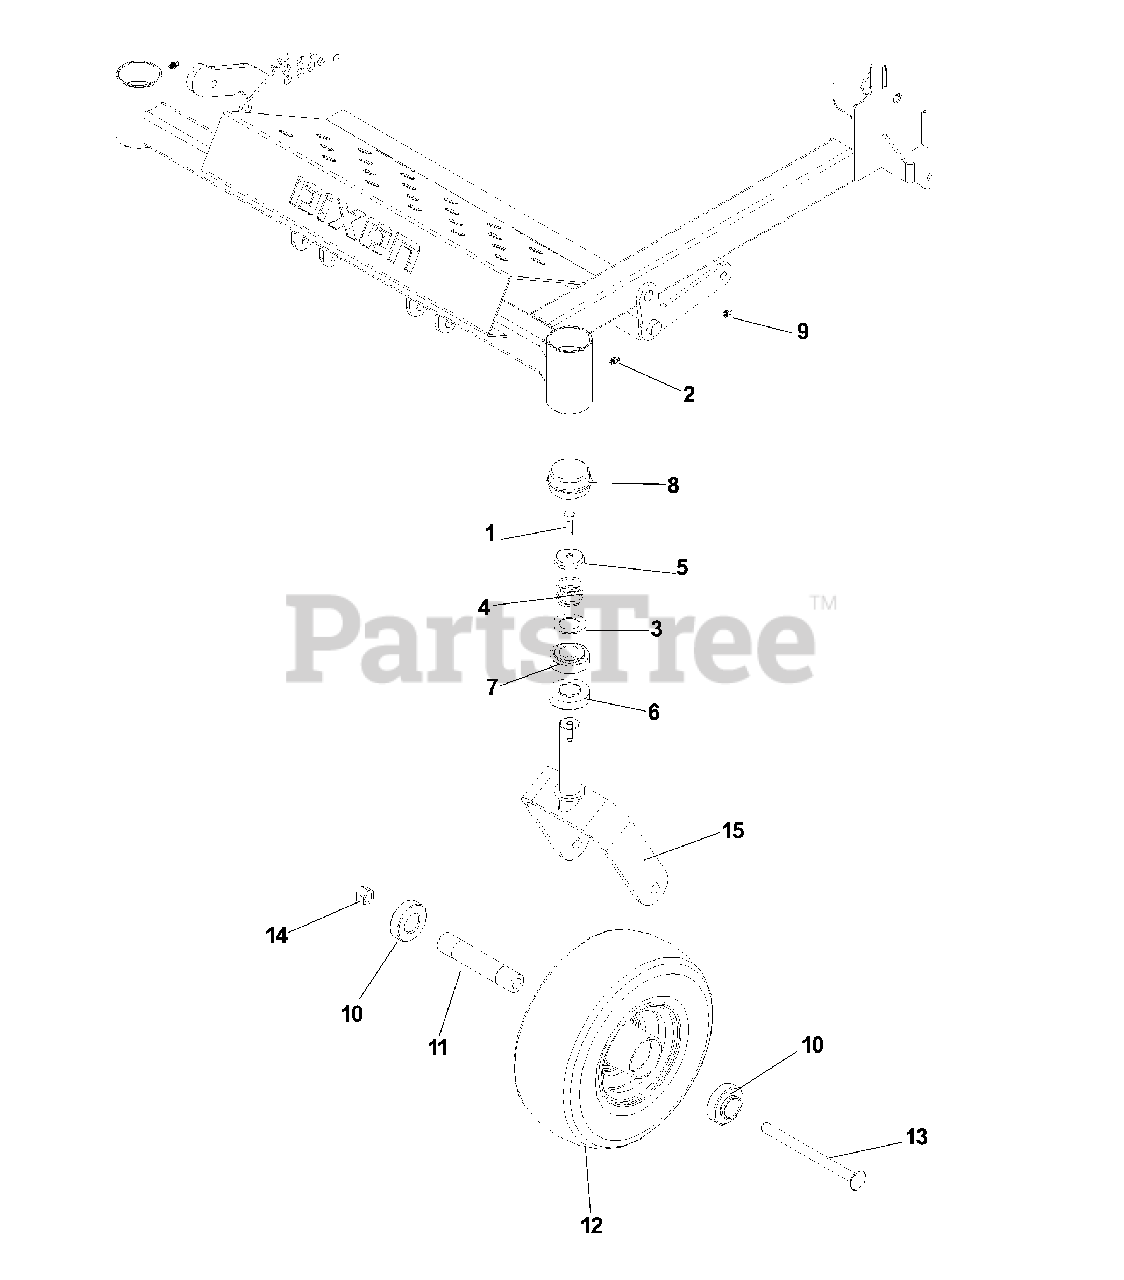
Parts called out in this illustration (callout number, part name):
1	5/16-18X1 HHB G5W/NY
2	ZERK, 3/16, DRIVE IN
3	WASHER, 1.025 ID X 1.64
4	SPRING, CASTER
5	CASTER.PLUG
6	BEARING
7	BUSHING, CASTER
8	GREASE CAP
9	GREASE ZERK-1/4"
10	BEARING-ECC LOCK
12	CASTER WHEEL AND TIRE
13	RHSNB 1/2-13 X 6.50 GR2 ZD
14	NUT, HEX 1/2-13 W/NYLOK
15	CASTER DK BLUE
